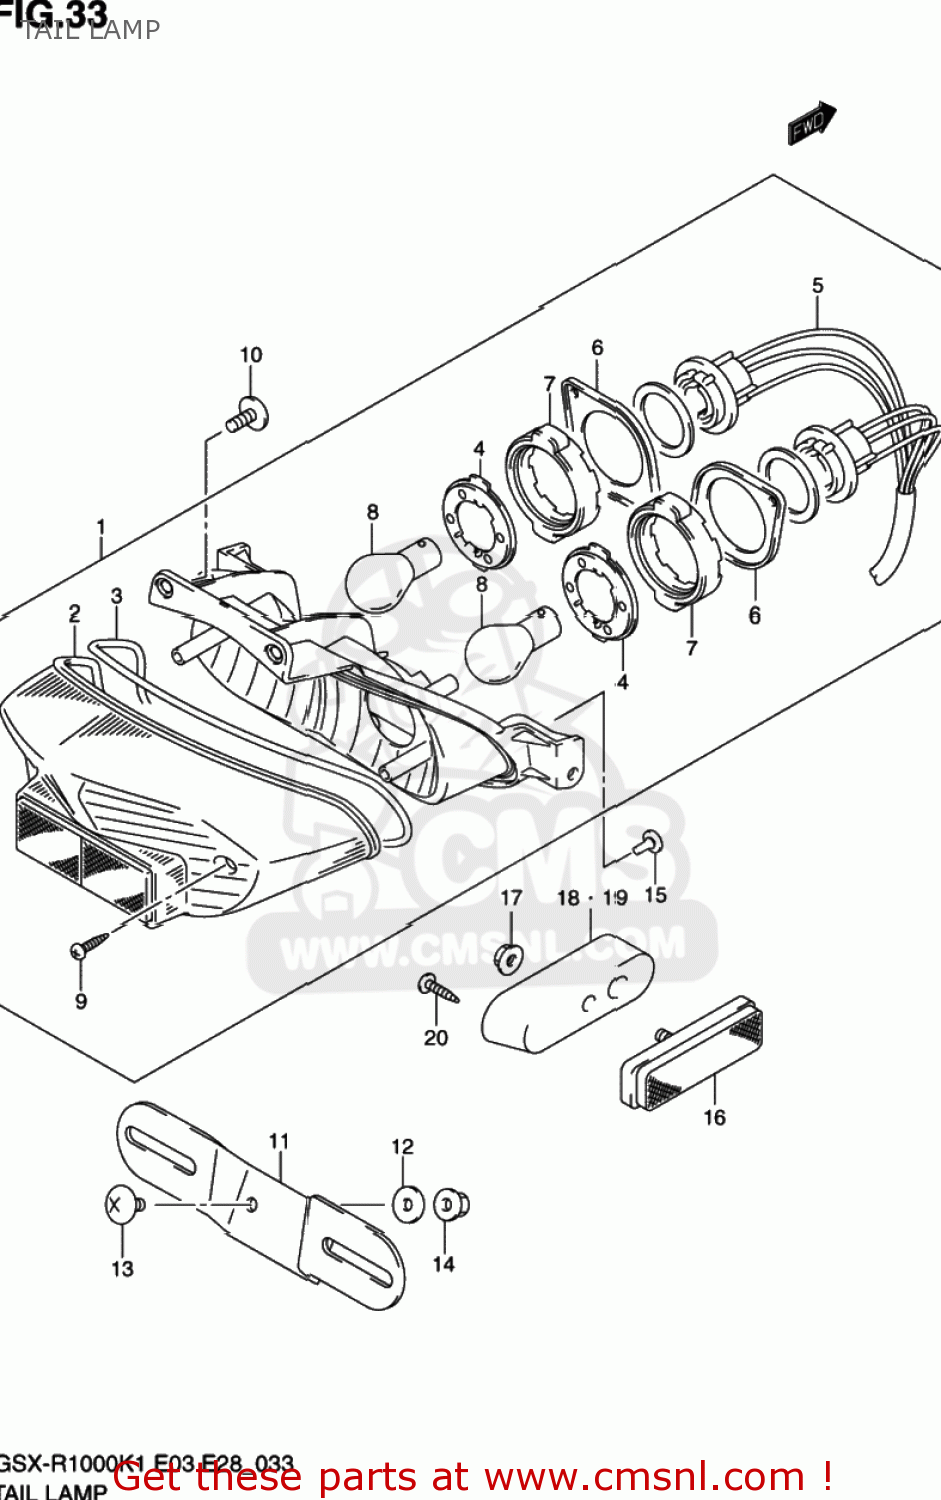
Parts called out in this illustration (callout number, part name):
1	LAMP ASSY,RR COMBINATION
2	LENS
3	GASKET (NAS)
4	PLATE NO.1
5	SOCKET & CORD
6	PLATE NO.2
7	CUSHION
8	BULB(12V21/5W)
9	SCREW
10	SCREW
11	BRACKET,LICENSE PLATE
12	WASHER(6.5X20X1.6)
13	SCREW 6X12
14	NUT
15	CUSHION
16	REFLECTOR ASSEMBLY,REAR
17	NUT
18	SPACER,RR SIDE RR,R
19	SPACER,RR SIDE RR,L
20	SCREW
